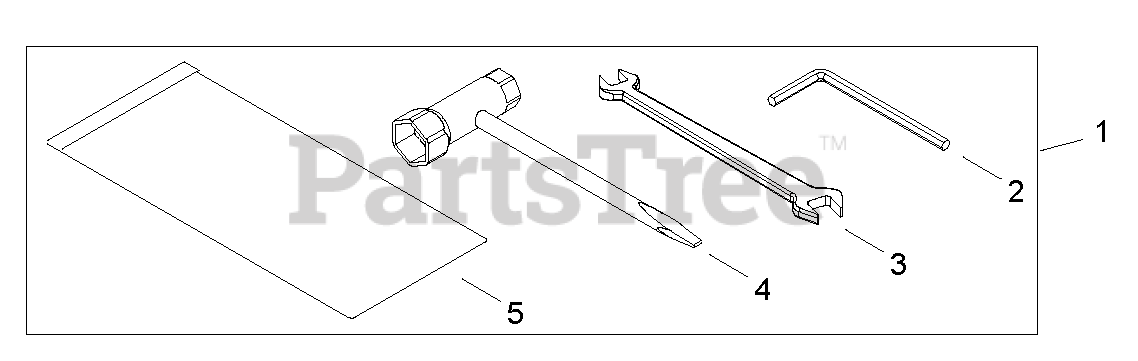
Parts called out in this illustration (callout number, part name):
1	TOOL KIT, SERVICE
2	WRENCH, ALLEN 4 MM
3	SPANNER 8×10
4	T-WRENCH 16×13
5	BAG, TOOL
